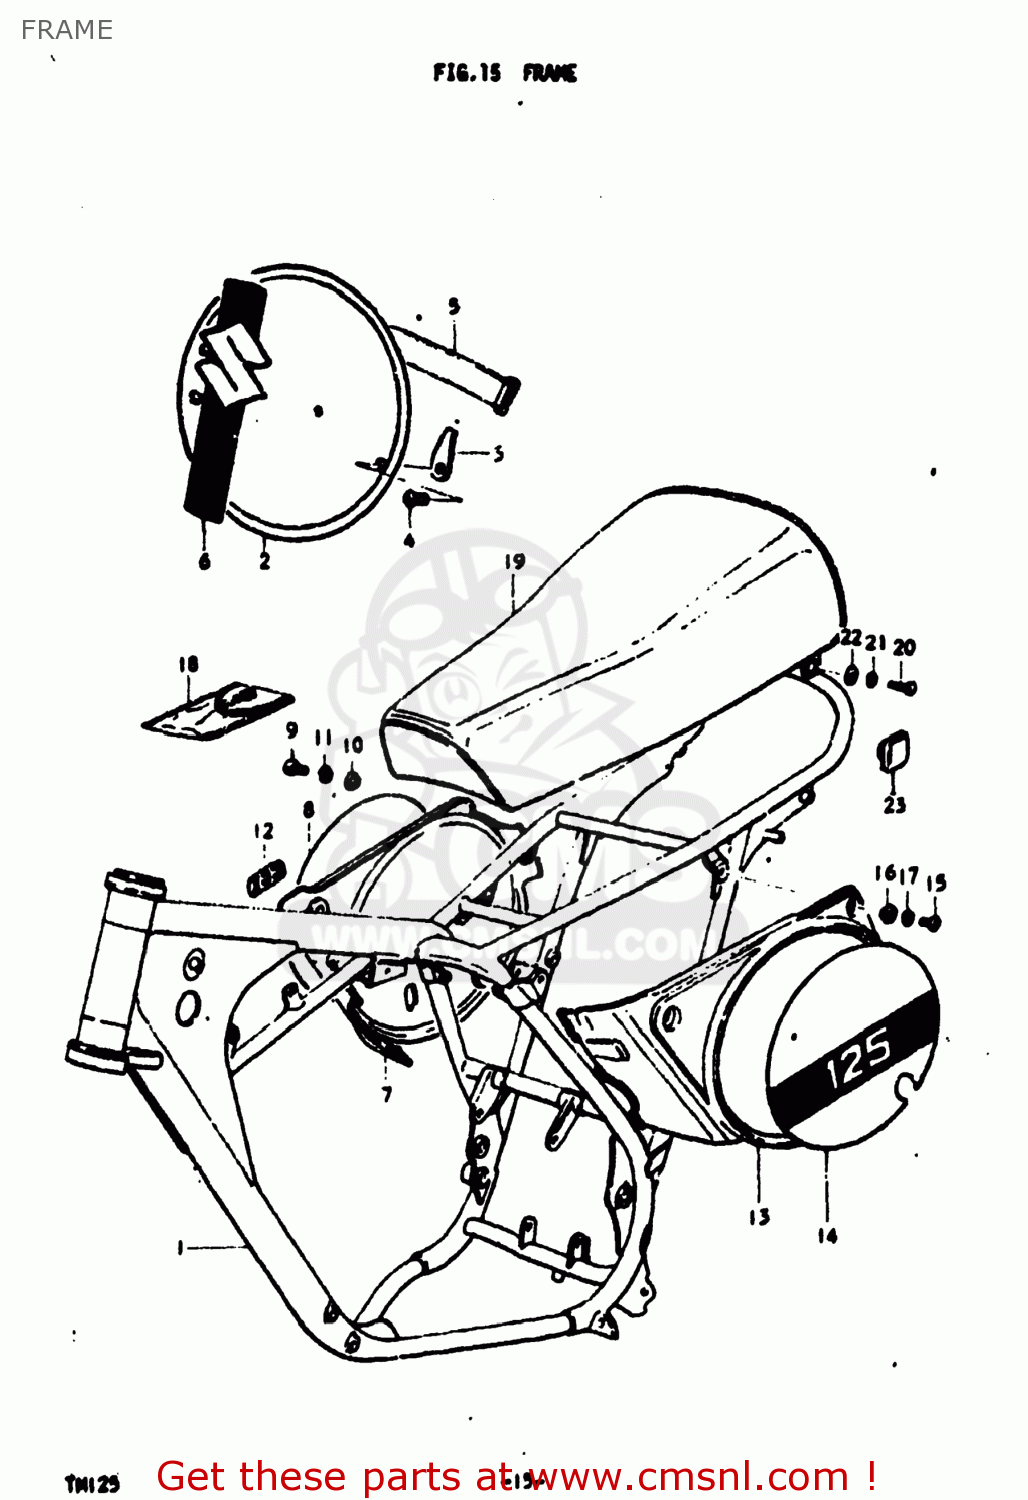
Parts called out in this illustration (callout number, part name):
1	FRAME
2	PLATE SET,FRONT
4	SCREW 6X12
5	BAND
6	EMBLEM,FRONT NUMBER PLATE
7	COVER,FRAME,RIGHT
8	EMBLEM
9	SCREW 6X12
10	WASHER
11	LOCK WASHER
12	EMBLEM,CCIS
13	COVER,FRAME,LEFT
14	EMBLEM,FRAME COVER
15	SCREW 6X12
16	WASHER
17	LOCK WASHER
19	SEAT ASSEMBLY
20	BOLT
21	LOCK WASHER
22	WASHER
23	CUSHION
